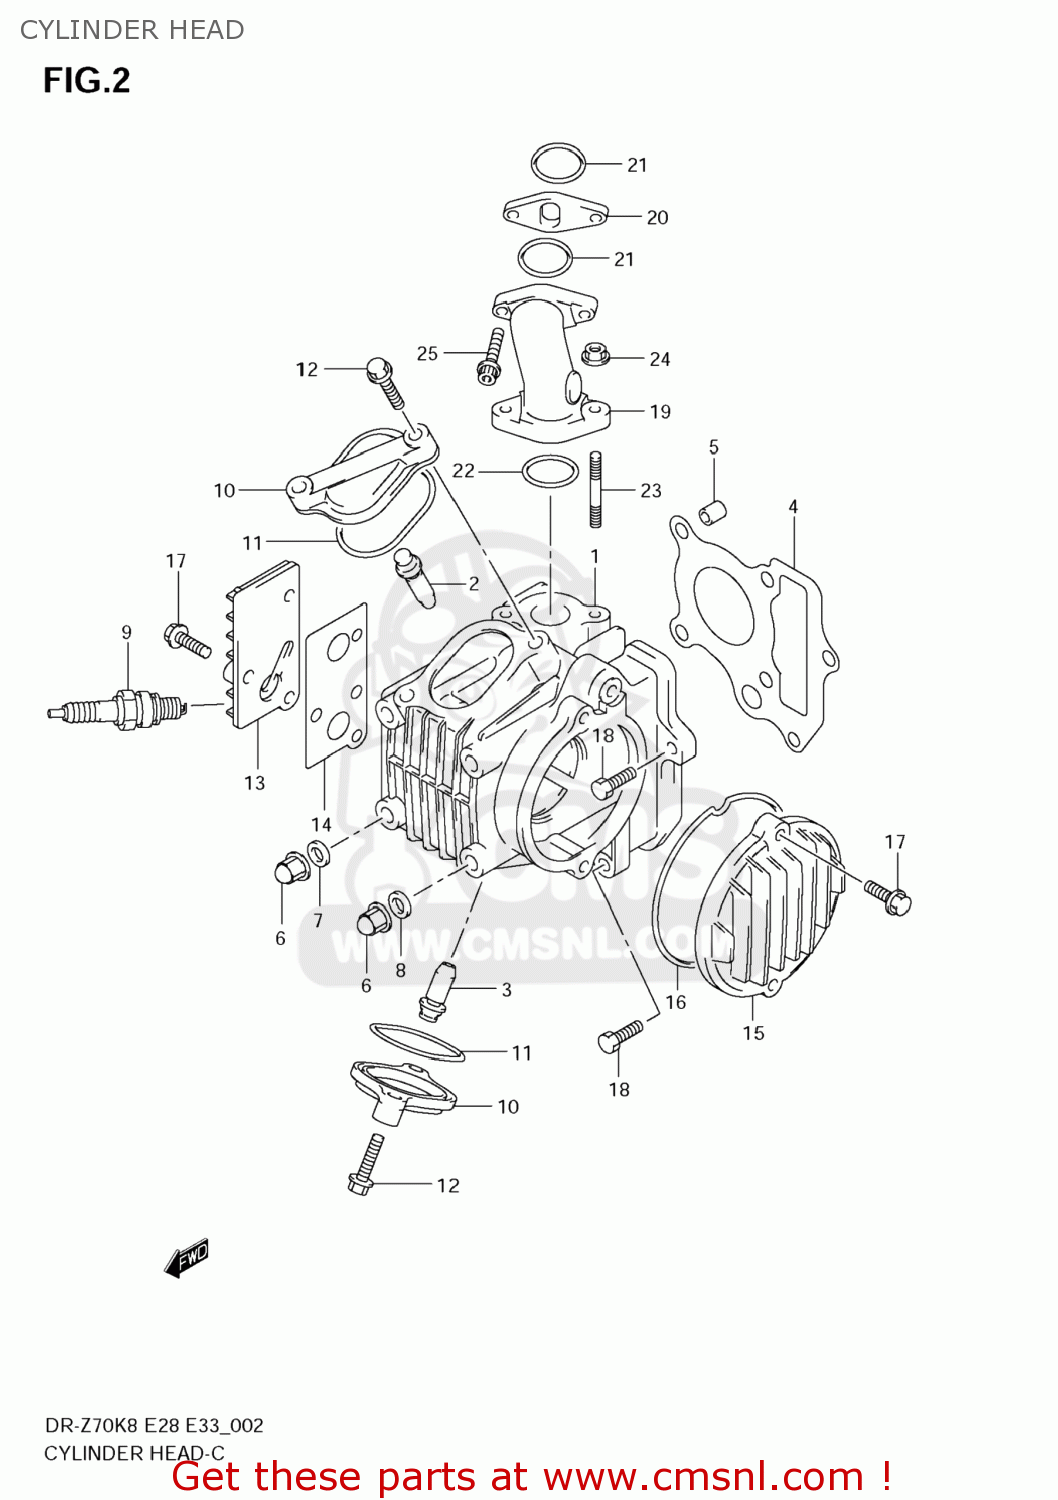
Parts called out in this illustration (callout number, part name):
1	HEAD,CYLINDER
2	GUIDE,INTAKE VALVE
3	GUIDE,VALVE
4	GASKET,CYLINDER HEAD (NAS)
5	PIN(6.2X8X11)
6	NUT
7	GASKET(6.5X13X2.3) (NAS)
8	WASHER(6.5X14X2.3)
9	PLUG,SPARK(CR7HSA)
10	CAP,INSPECTION
11	O RING(D:2.4,ID:33.6X48.6)
12	BOLT
13	COVER,CYLINDER HEAD,R
14	GASKET,CYL HEAD COVER,R(NA) (NAS)
15	COVER,CYLINDER HEAD,L
16	O RING(D:2.4,ID:73.5)
17	BOLT
18	BOLT
19	PIPE,INTAKE
20	INSULATOR,CARBURETOR
21	O RING(D:1.9,ID:21.8)
22	O RING(D:2.4,ID:23.7)
23	BOLT,STUD
24	NUT
25	BOLT
